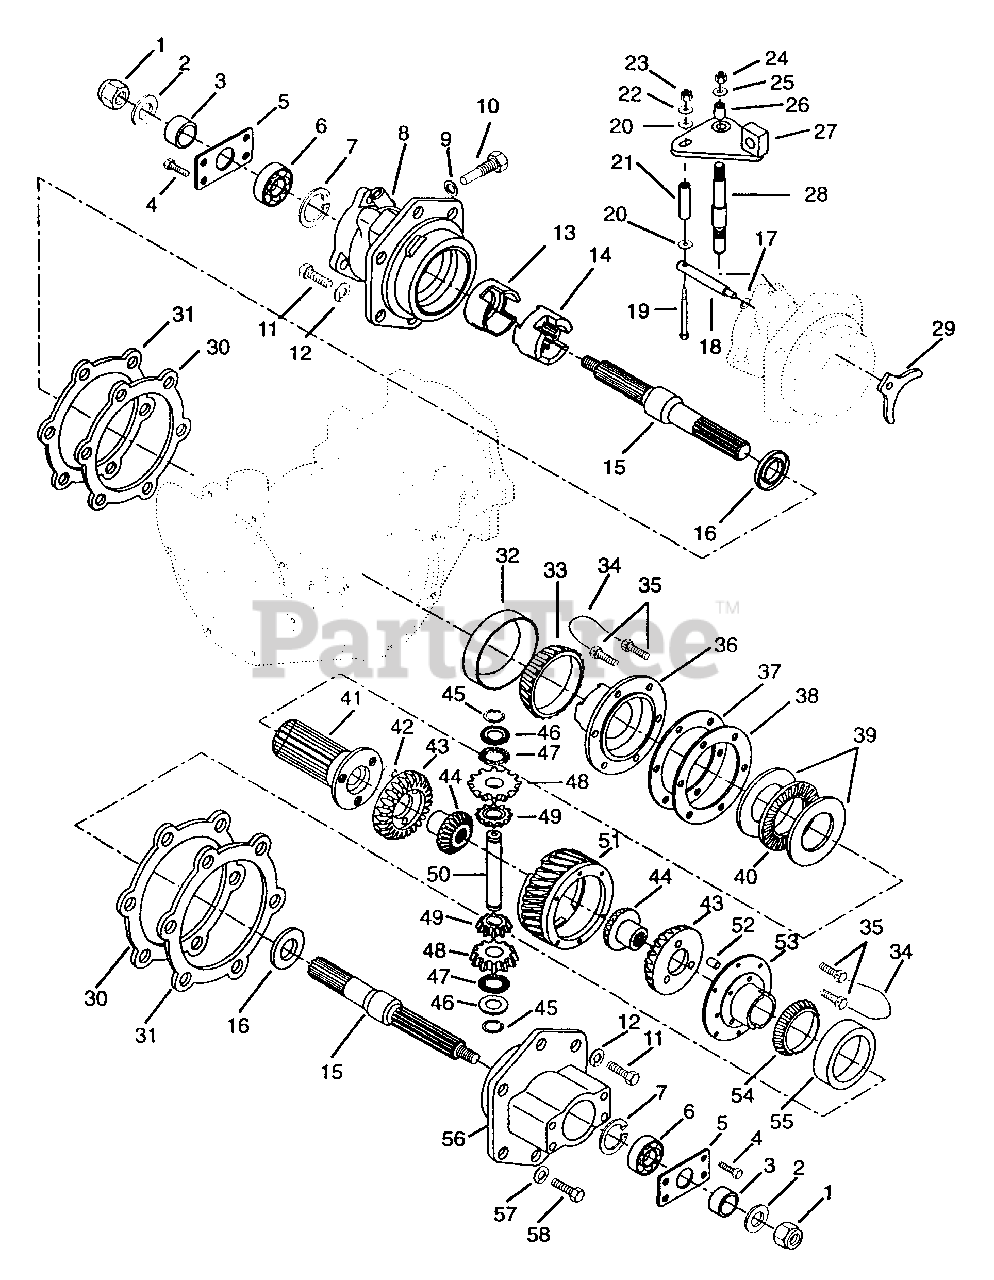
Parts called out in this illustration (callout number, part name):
1	Nut-Locking-Jam-Nylon .75-10
2	Washer-Flat .812 x 1.469 x .134
3	Spacer 1.008 x 1.377 x .509
4	Bolt-Hex.38-16 x.75 Grade 5
5	Plate, End
6	Bearing-Ball 1.0 x 2.0 x .56
7	Ring-Retaining-Internal 2.210 x .062
8	Housing, Axle, 2 Speed
9	Washer-Nut .63 x .875 x .062
10	Bolt-Hex .62-18 x .493 x 1.25
11	Bolt-Hex .50-13 x 1 Grade 5
12	Washer-Lock .50 Reg.
13	Clutch, Stationary
14	Clutch, Shifting
15	Axle, Straight
16	Seal 1.188 x 2.000 x .250
17	O-Ring .437 x .625 x .093
18	Pin, Clutch Sliding
19	Bolt-Round Head Square Neck .25-20 x 2.25 Grade 8
20	Washer-Flat-Steel .406 x .812 x .065
21	Bushing, Sleeve .277 x .375 x 1.37
22	Washer-Flat-Steel .281 x .625 x .065
23	Nut-Locking-Nylon .250-20 Grade 2
24	Nut-Locking-Nylon .312-18 Grade 2
25	Washer-Flat-Steel .344 x .688 x .065
26	Bushing-Sleeve .377 x .503 x .88
27	Weldment, Arm Shifter
28	Pivot, Stationary
29	Yoke, Shifting
30	Gasket, Axle Housing
31	Assembly, Advance Casting
32	Bearing-Race 4.34 x .741
33	Bearing-Cone 2.69 x .87
34	Wire, Bolt
35	Bolt-Special .31-18 x .75
36	Housing Clutch
37	Shim, .020 Clutch Worm Gear
38	Shim, .005 Clutch Worm Gear
39	Washer-Thrust 2.002 x 2.740 x.031
40	Bearing-Needle-Thrust 2.0 x 2.74 x .010
41	Shifter, Splined Pinned
42	Pin-Dowel .375 x .375
43	Gear, Pinned Bevel
44	Gear, Differential Bevel
45	Ring-Retaining .697 x .93
46	Bushing, Flange .761 x 1.24 x 1.24
47	Bearing-Needle-Thrust .754 x 1.24 x .078
48	Gear, Differential Shifting Bevel
49	Gear, Spider Bevel
50	Pin, Spider
51	Gear, Worm & Start
51	Gear, 6-Lead Worm
52	Pin-Dowel .38-x .500
53	Housing, Pinned
54	Cone, Roller Bearing 50 MM x 21.5 MM
55	Cup, Roller Bearing 82 MM x 17 MM
56	Housing, Axle
57	Seal-Oil Drain .563 x 1.250 x .091
58	Bolt-Hex .50-13 x 1.312 Grade 5
